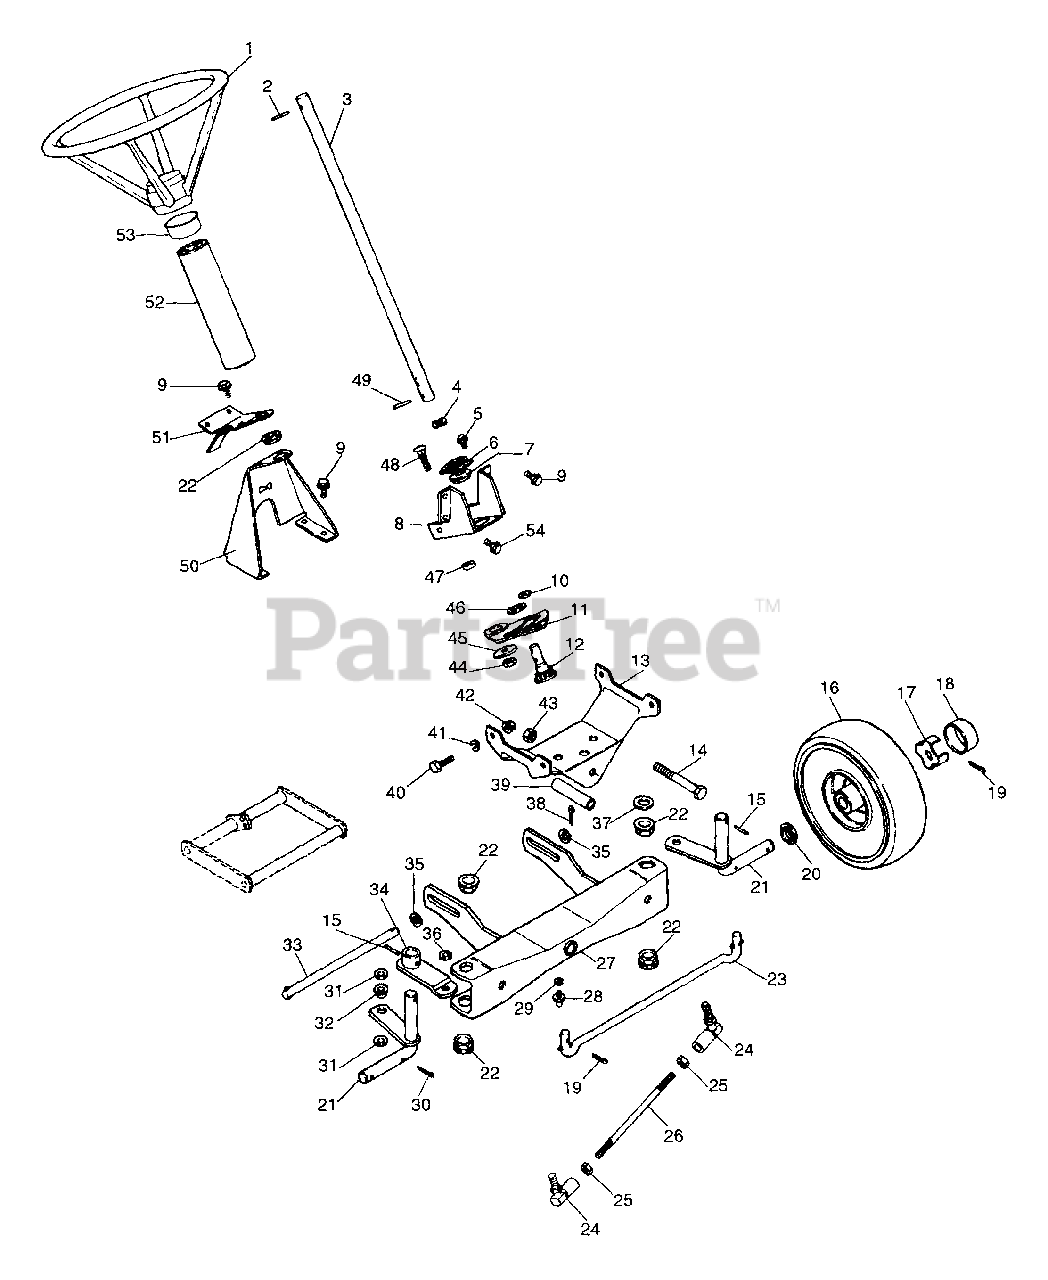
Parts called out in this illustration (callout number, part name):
1	STEERING WHEEL
2	PIN-ROLL .250X1.75
3	STEERING SHAFT
4	WSHR-HDND-STL-THR.515X.97X.062
5	SCR-TAP 10-24X.25 CRSLPH PL 1A
6	RETAINING PLATE
7	BSHG-FLG .625X1.156X.375 SI
8	STEERING BRACKET
9	SCR-TAP .312-18X.50 HWH PL TR
10	NUT-LK .375-24 PL
11	STEERING GEAR
12	PINION
13	AXLE BRACKET
14	BLT-HEX .50-13X4.00 PL GR2
15	PIN-GRV .250X1.25 TP A
16	T/WHL ASSY
16	TIRE 4.10/3.50-4
16	ZERK FITTING
16	WHL
16	BSHG-FLG .750X1.380X.750X1.557
16	BRG-BALL .752X1.50X.50
16	WHL-COMP
17	SPINDLE CUP
18	HUB CAP
19	PIN-COTR .12X1.0 PL
20	SPINDLE WASHER
21	R.H. WHEEL SPINDLE
21	L.H. WHEEL SPINDLE
22	FLANGE BUSHING
23	TIE ROD
24	BALL JOINT
25	NUT .375-24 PL
26	STEERING LINK
27	AXLE
28	SPIN DRIVE ZERK FITTING
29	WSHR-FL-STL .265X.500X.087 PL
30	PIN-COTR .12 X 1.25 PL
31	WSHR-FL-STL .505X.875X.024 PL
32	BSHG-FLG.500X.625X.312X.750NY
33	HANGER PIN
35	WSHR-FL-STL .505X.880X.072 PL
36	WSHR-FL-STL.406X.812X.065PL
37	WSHR-FL-STL .755X1.375X.062 PL
38	PIN-COTR .09X.75 PL
39	TUBE AXLE PIVOT
40	BLT-SERRDHD SL .31-18X.75 YZ
41	WSHR-LK .375X.094 MED PL
42	NUT-FLG. .312-18 PL
43	NUT-LK-CTR .50-13
44	NUT-LK-JAM-CTR .375-16 PL
45	WSHR-FL-STL .390X1.500X.125
46	WSHR-FL-STL .630X1.250X.062 PL
47	SPACER .380X.750X.236
48	BLT-RDHDSQSHNK .38-16X1.00 PL
49	SEAL 1.125X1.929X.625
50	STEERING SUPPORT
54	SCR-TAP .312-18X.50 PL F
